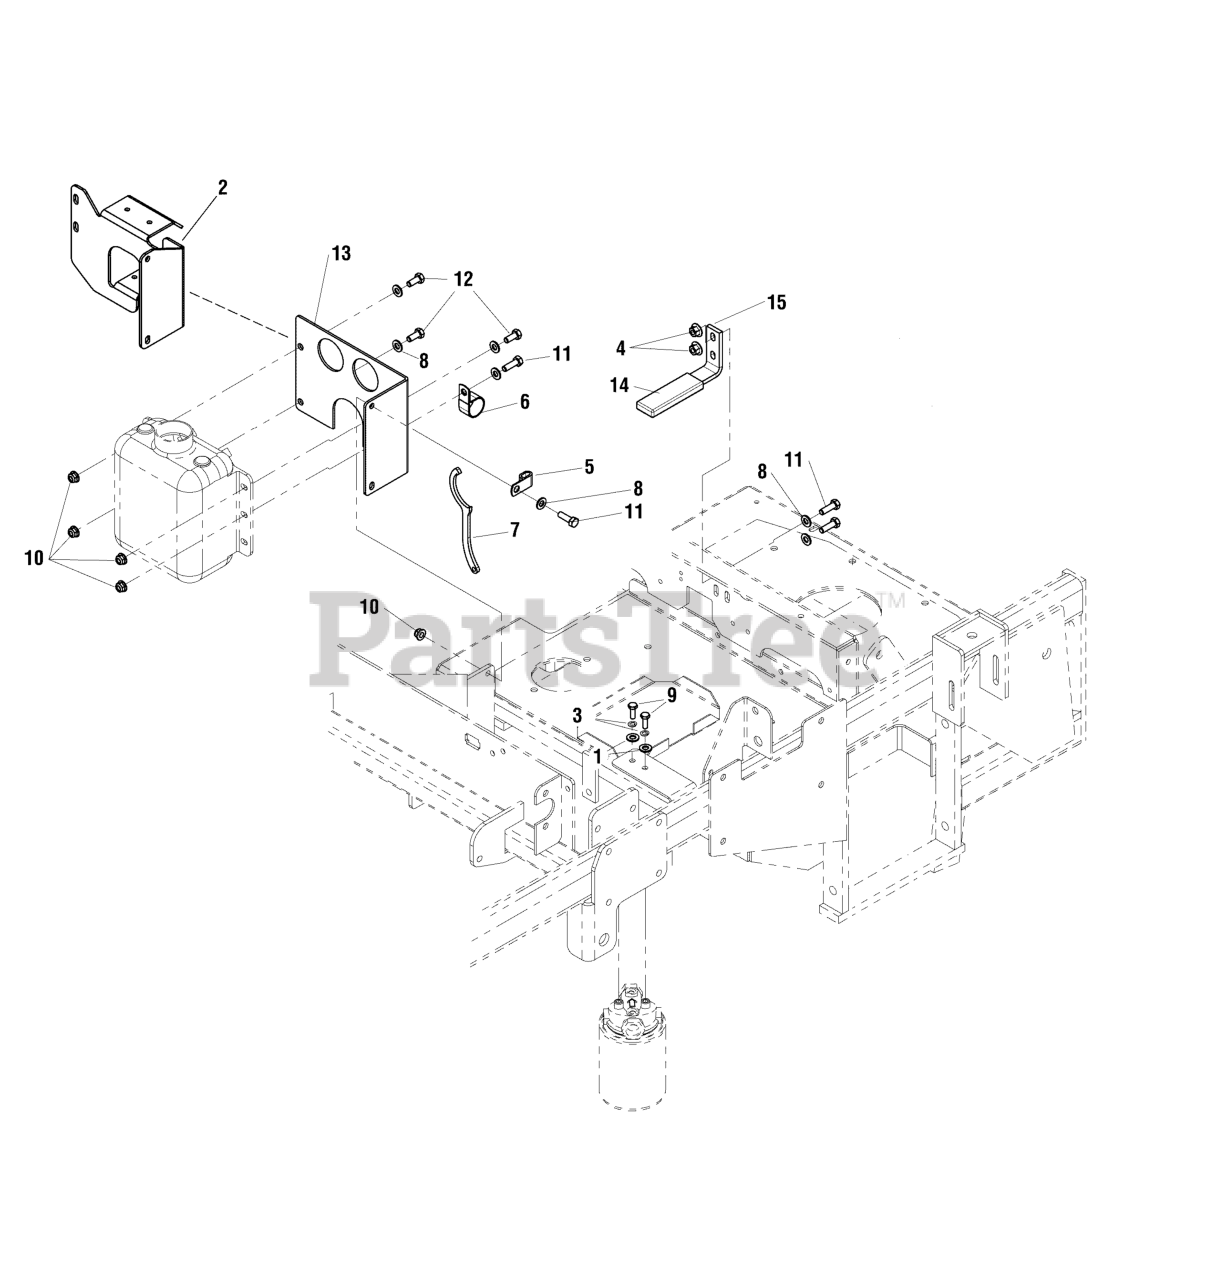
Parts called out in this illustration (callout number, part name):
1	WASHER, 1/4 SAE
2	MOUNT, HYDRO TANK W/ SUPPORTS
3	WASHER, 1/4 LOCK
4	NUT, 5/16-18 HEX SERRATED FLANGE (LARGE)
5	CLAMP, 5/16", DOUBLE, WIRE & TUBE
6	CLAMP, HOSE, 1.000 DIA.
7	WRENCH, SPANNER, CZ
8	WASHER, 5/16" SAE
9	BOLT, 1/4-20 X 3/4" GD5 YZ
10	NUT, 5/16-18 HEX NYLOCK FLANGE
11	BOLT, 5/16-18 X 1" GD5 YZ
12	BOLT, 5/16-18 X 3/4 GD5
13	MOUNT, HYDRO TANK - RED
14	GRIP, FOAM, 1/4 X 1 X 4.1
15	RETAINER, BATTERY - RED
